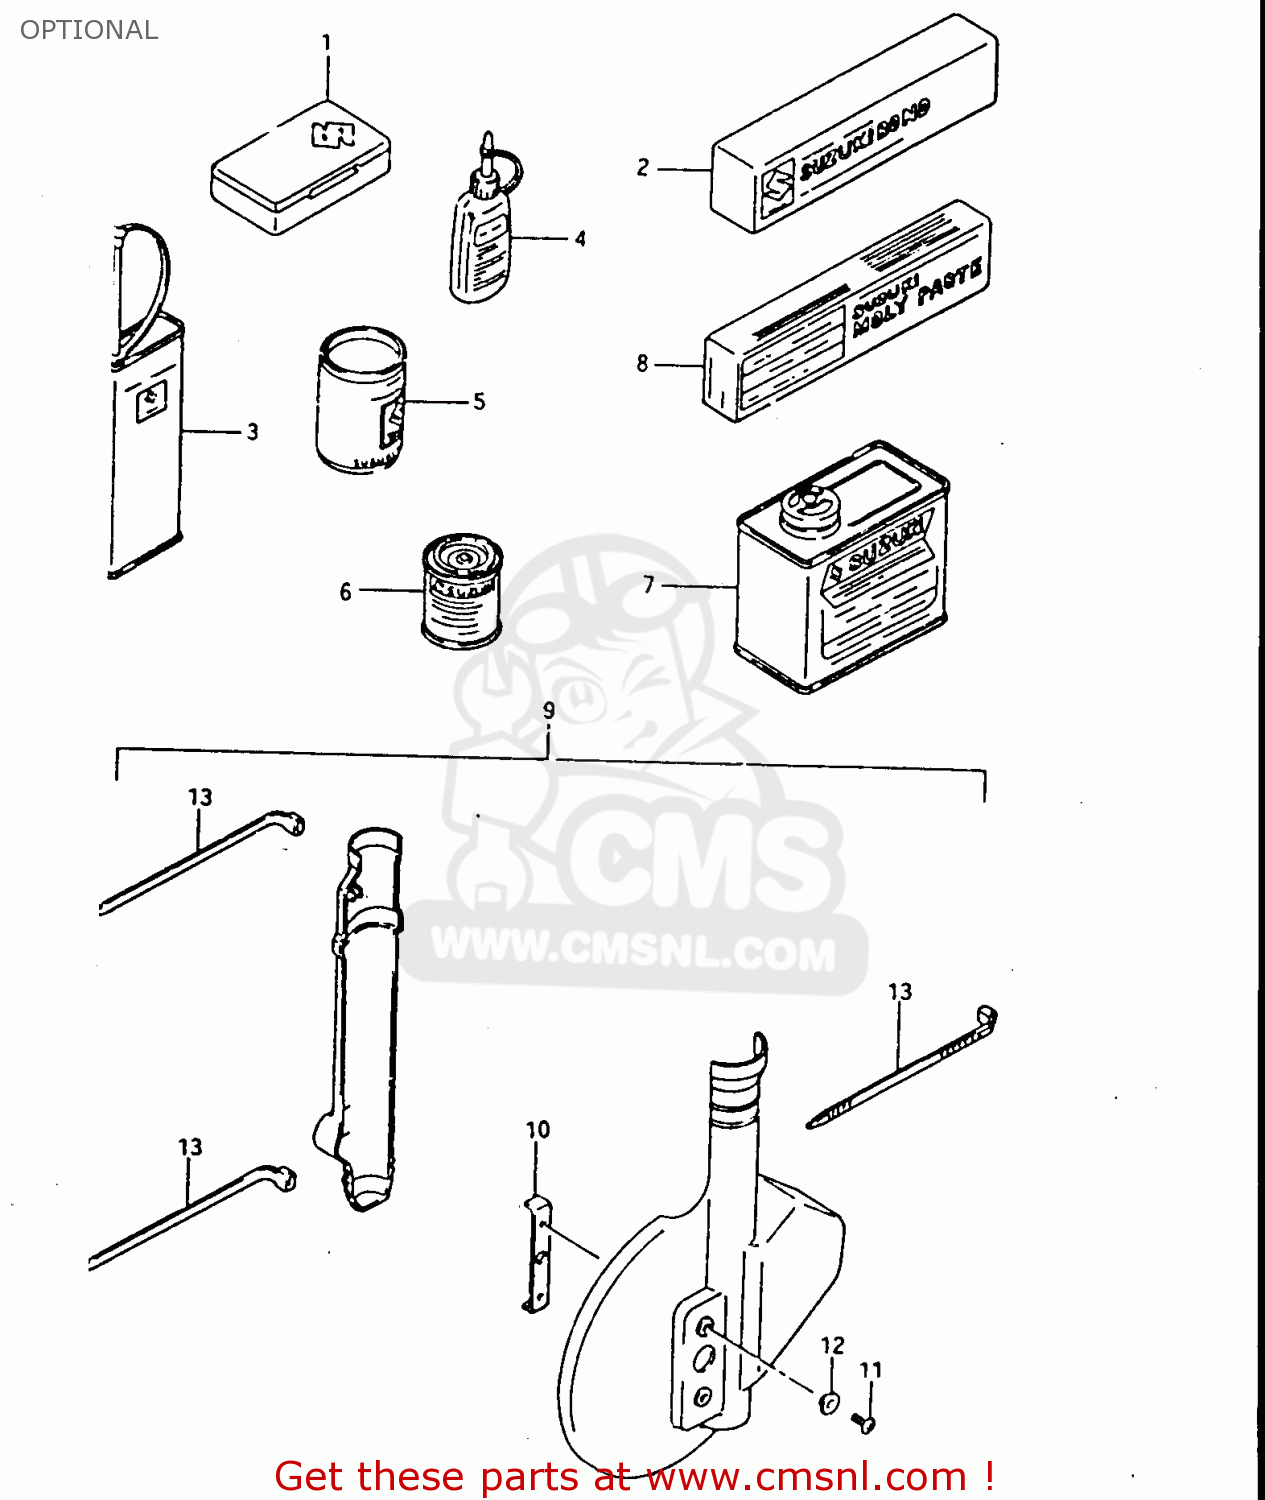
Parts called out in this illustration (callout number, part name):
1	TOOL, TUBE REPAIRING
2	LIQUID GSKT NO.1207B 100G BLK
3	THREAD LOCK NO.1401 CLEAR 200G
4	THREAD LOCK NO.1342
5	GREASE(C)EP2 LITHIUM 150G
6	PAINT,BLACK
7	PAINT (BLACK)
8	SUZUKI MOLY PASTE
9	PROTECTOR SET, FRONT FORK (WHITE)
10	PLATE, PROTECTOR
11	SCREW 6X12
12	WASHER
13	CLAMP
